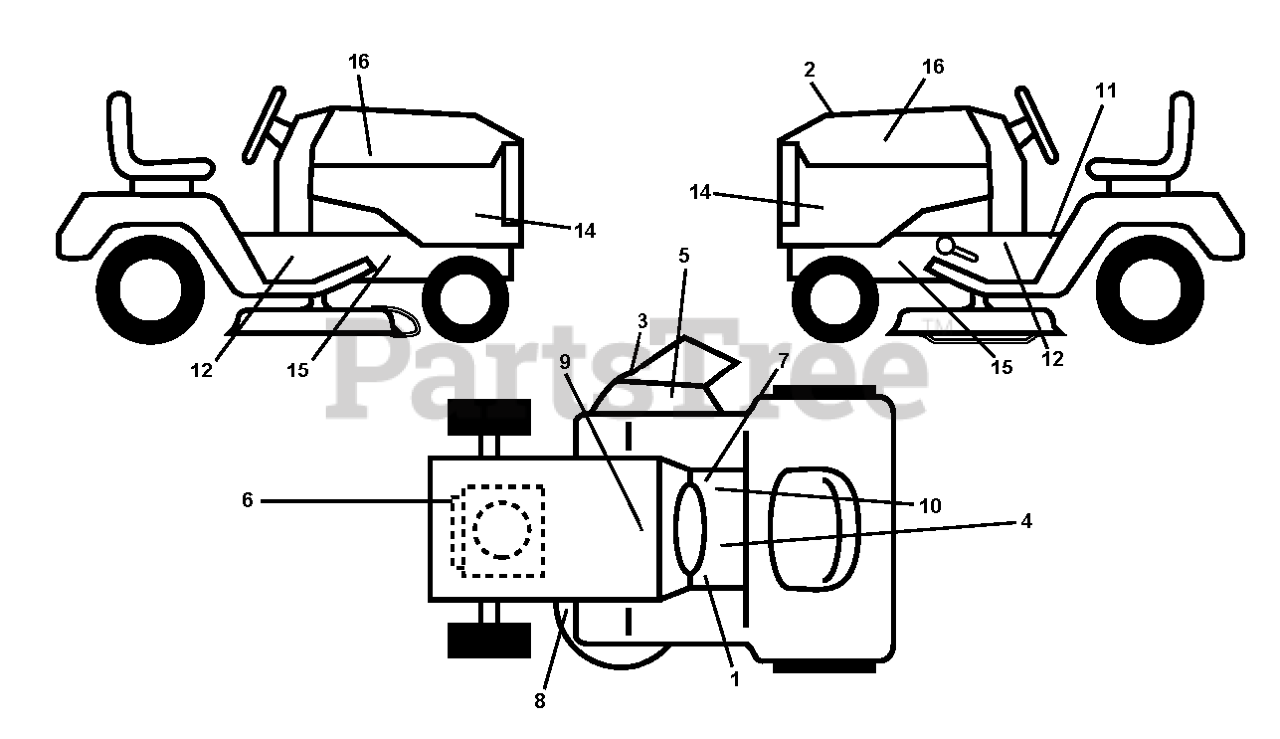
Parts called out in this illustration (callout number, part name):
1	DECAL
3	DECAL, DEFLECT WARNING
4	Decal, Fender 100 DB/CE
5	DECAL.INTERNATIONL.CUTFINGER
6	DECAL
7	DECAL PARK BRAKE
8	DECAL V BELT SCHEMATIC
9	DECAL BTRY SYMBOLS
10	DECAL
11	LABEL
16	DECAL.HOOD.LOGO.ORANGE.HUSQVAR
